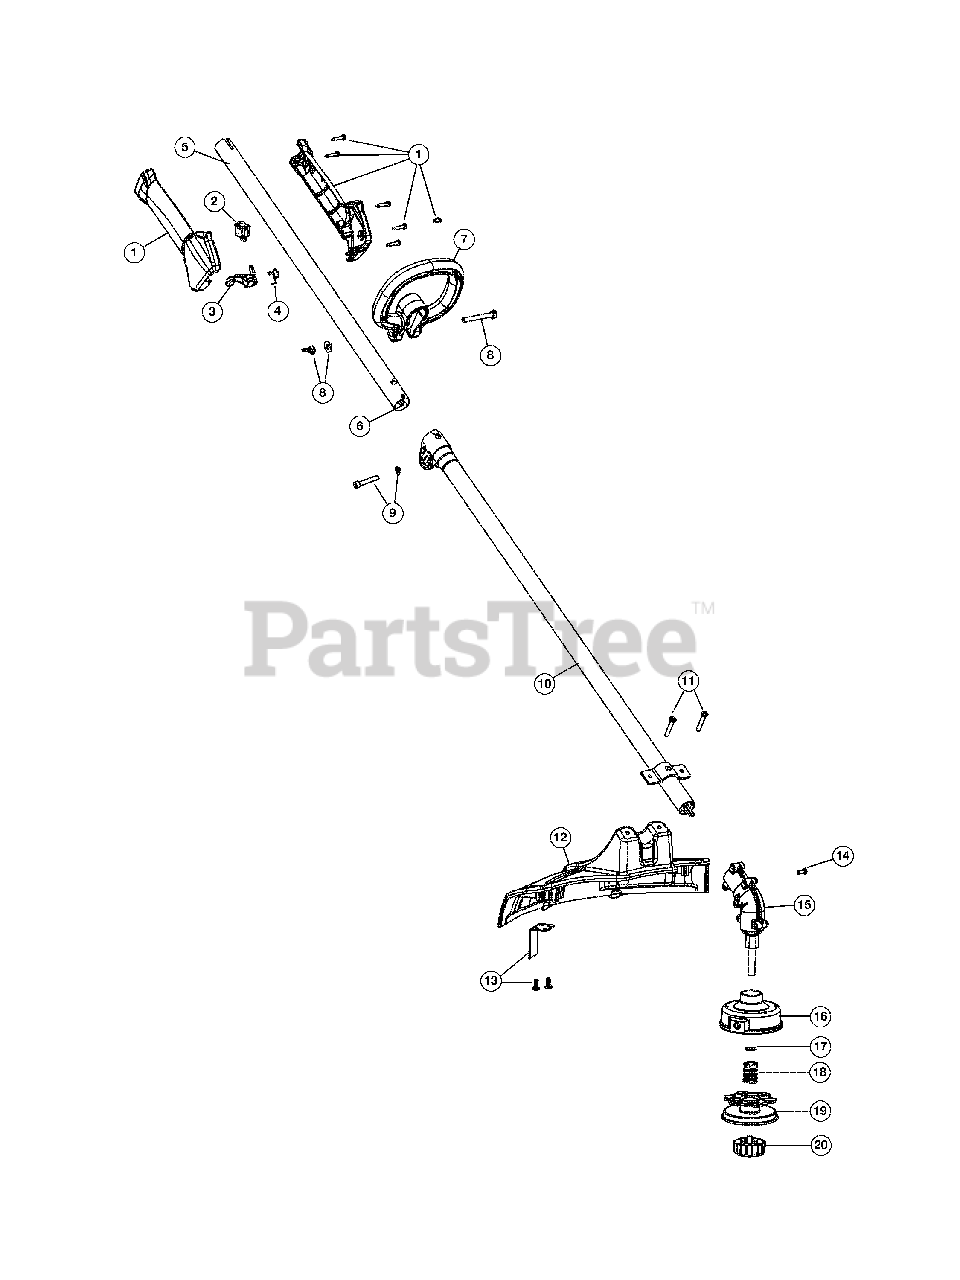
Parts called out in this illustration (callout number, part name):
1	Throttle Housing Assembly (includes 2-4)
3	Throttle Trigger
4	Throttle Trigger Spring
5	Upper Shaft Housing Assembly (includes 6)
6	Upper Flexible Drive Shaft
7	D-Handle (includes 8)
8	D-Handle Hardware Assembly
9	Clamp Hardware
10	Lower Shaft Housing Assembly
11	Shield Mounting Screw
12	Shield Assembly (includes 11 & 13)
13	Blade Assembly
14	Anti-Rotation Screw
15	Gearbox Assembly (includes 15-20)
16	Outer Spool Assembly (includes 17)
17	Retainer
19	Inner Reel
20	Bump Head Knob Assembly
